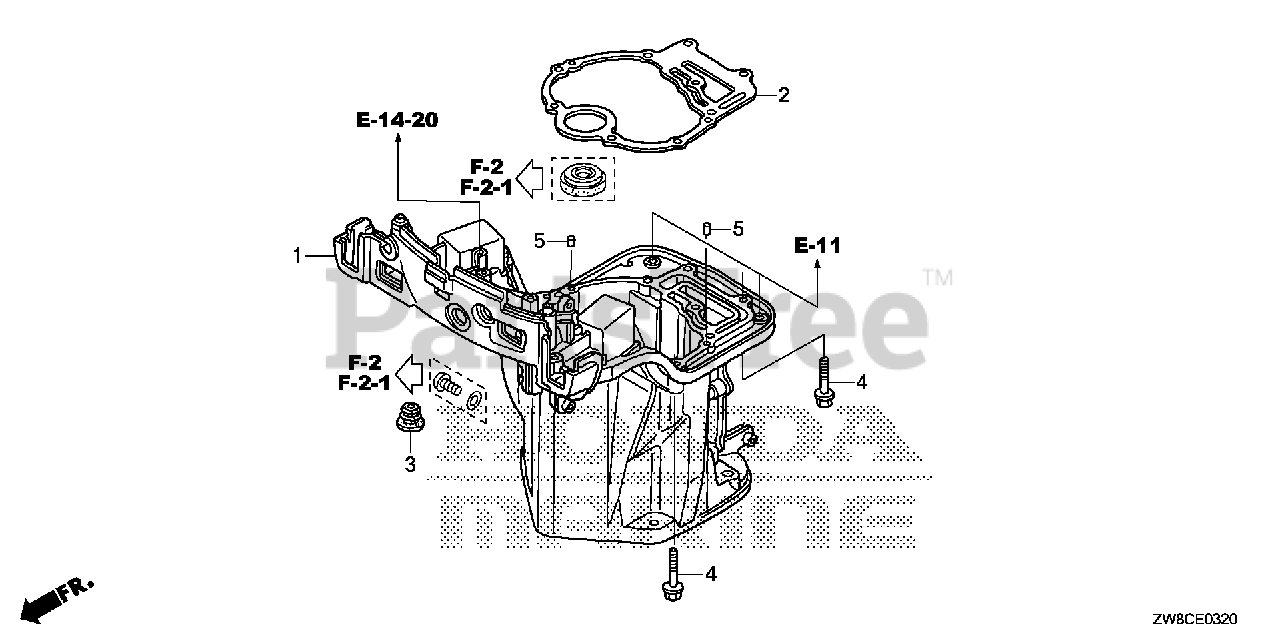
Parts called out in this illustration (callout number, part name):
1	CASE, OIL *NHB14M* (AQUA MARINE SILVER METALLIC)
2	GASKET, OIL PAN
3	GROMMET, WATER TUBE
4	BOLT, FLANGE (8X35) Use from Frame SN 4800713.
5	PIN A, DOWEL (6X10)
